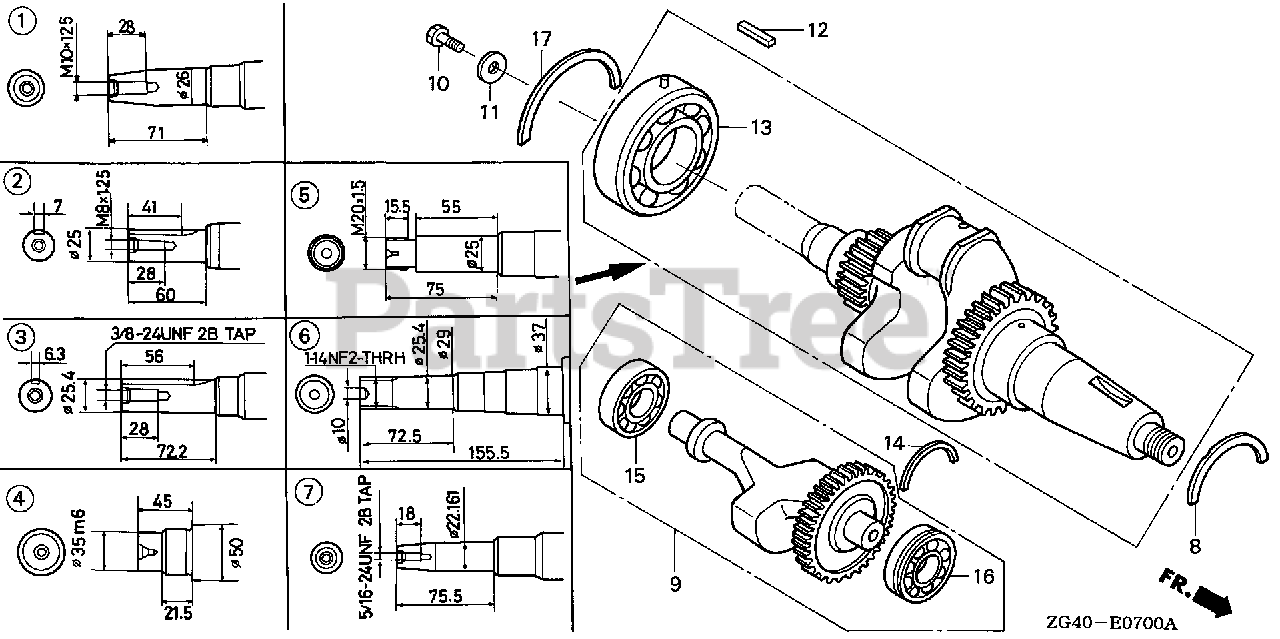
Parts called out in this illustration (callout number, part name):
3	CRANKSHAFT
8	BEARING A, CRANKSHAFT THRUST (BLUE)
9	WEIGHT, BALANCER
12	KEY (6.3X6.3X43)
13	BEARING, SPECIAL (6307)
14	SET-RING (470)
15	BEARING B, SPECIAL BALL (6204)
16	BEARING C, SPECIAL BALL (6204)
